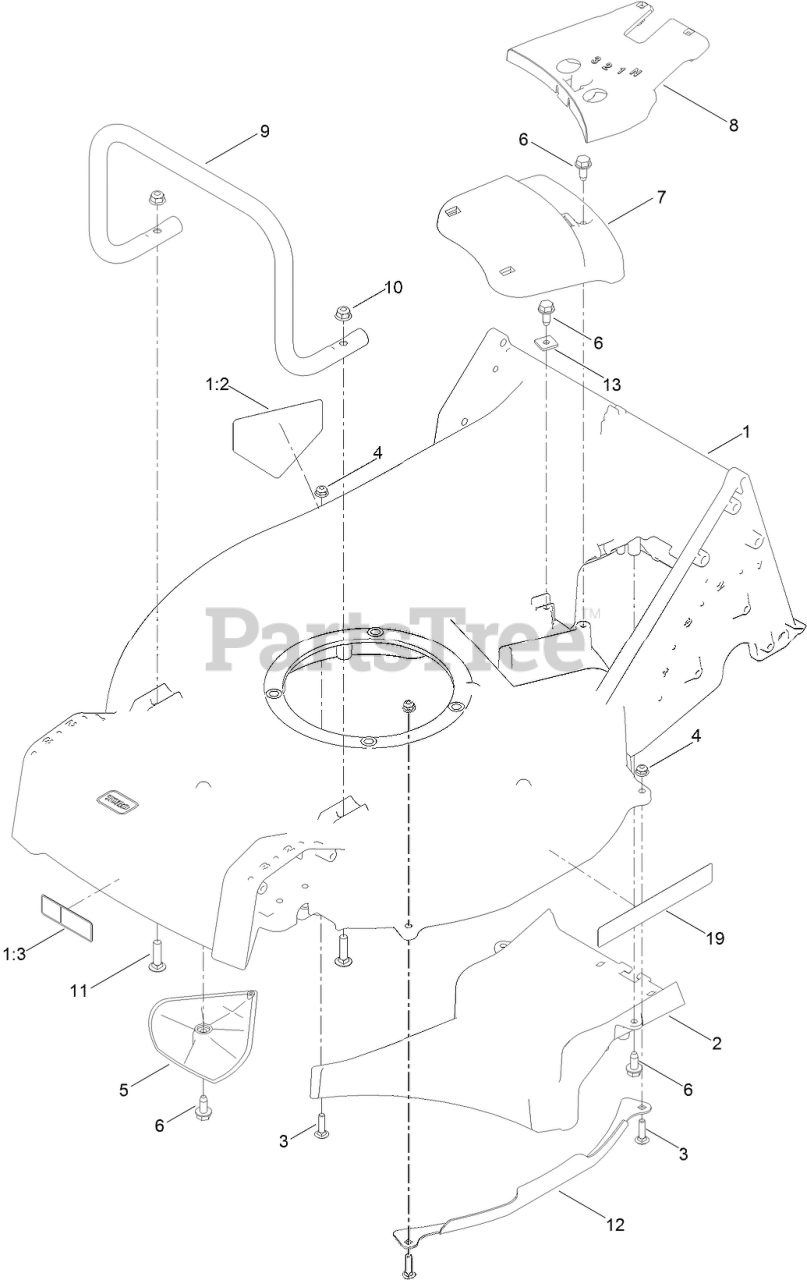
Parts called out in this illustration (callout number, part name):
1	HOUSING ASM
1:2	DECAL-DANGER
1:3	DECAL-WARNING, BLADE
2	FLOOR-CHUTE
3	SCREW-CARR
4	NUT-HF
5	KICKER
6	SCREW-HWHTF
7	COVER-BELT, FRONT
8	COVER-BELT, REAR
9	GUARD-ENGINE
10	NUT-HF, NI
11	SCREW-CARR
12	GUARD-SIDE, DECK
13	CLAMP-CABLE
19	DECAL-RECYCLER
